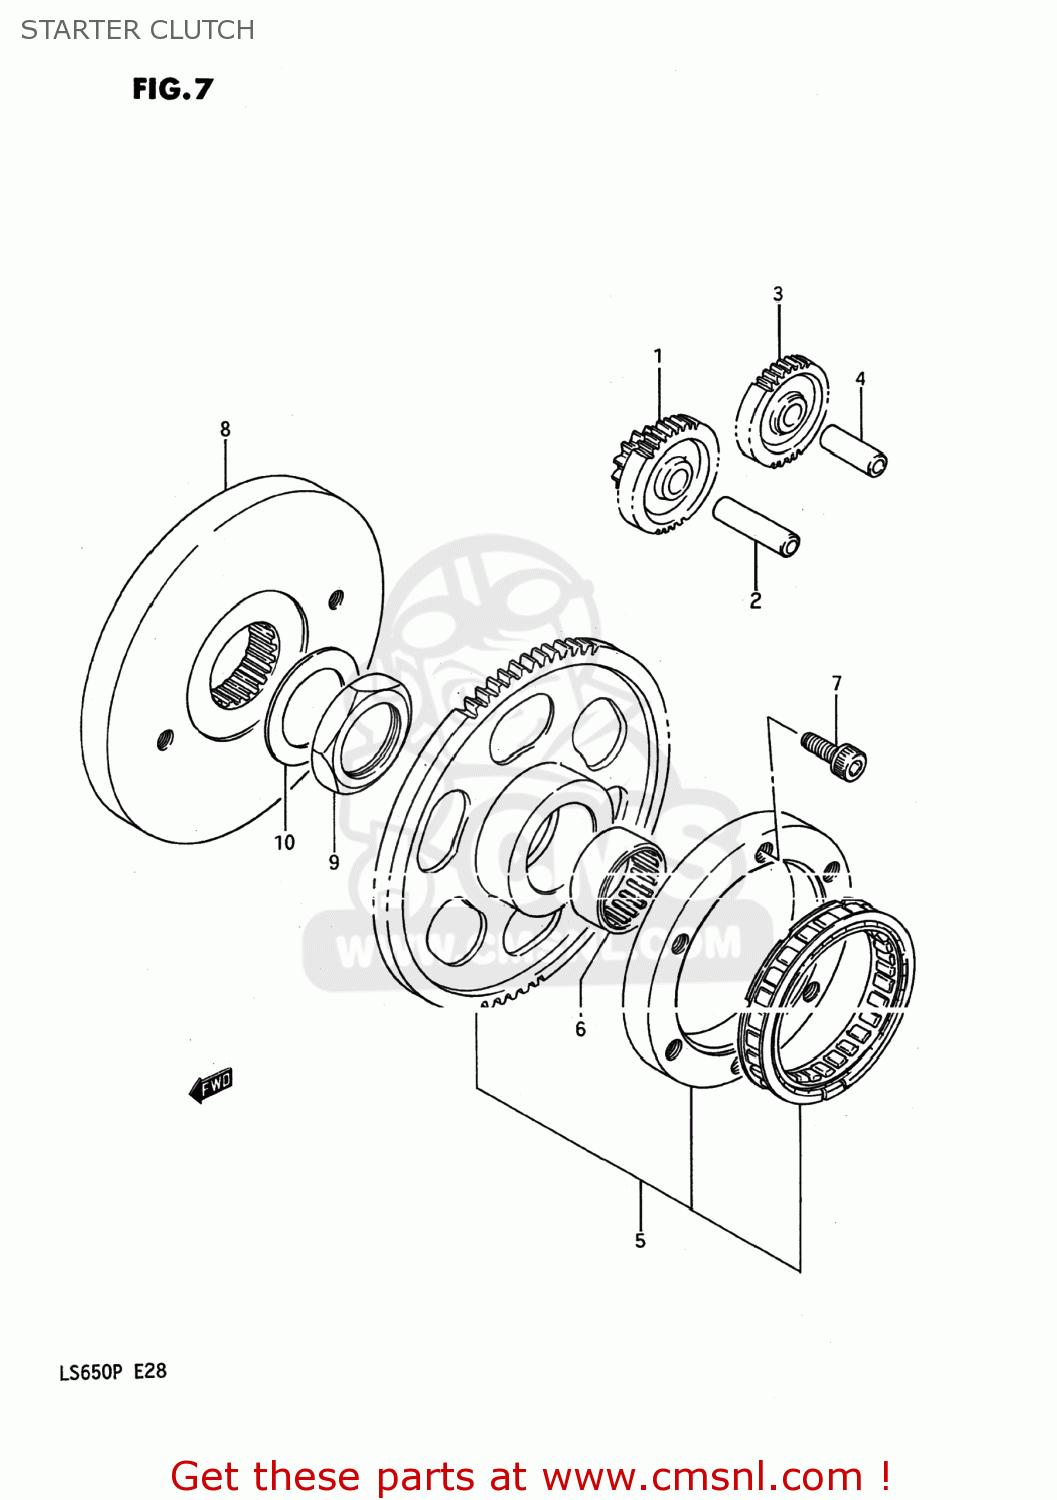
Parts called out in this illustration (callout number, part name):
1	GEAR,STARTER IDLE
2	PIN
3	GEAR,STARTER IDLE
4	PIN
5	CLUTCH SET,STARTER
6	BEARING(31X39X17.8)
7	BOLT
8	FLYWHEEL
9	NUT,FLYWHEEL
10	WASHER
